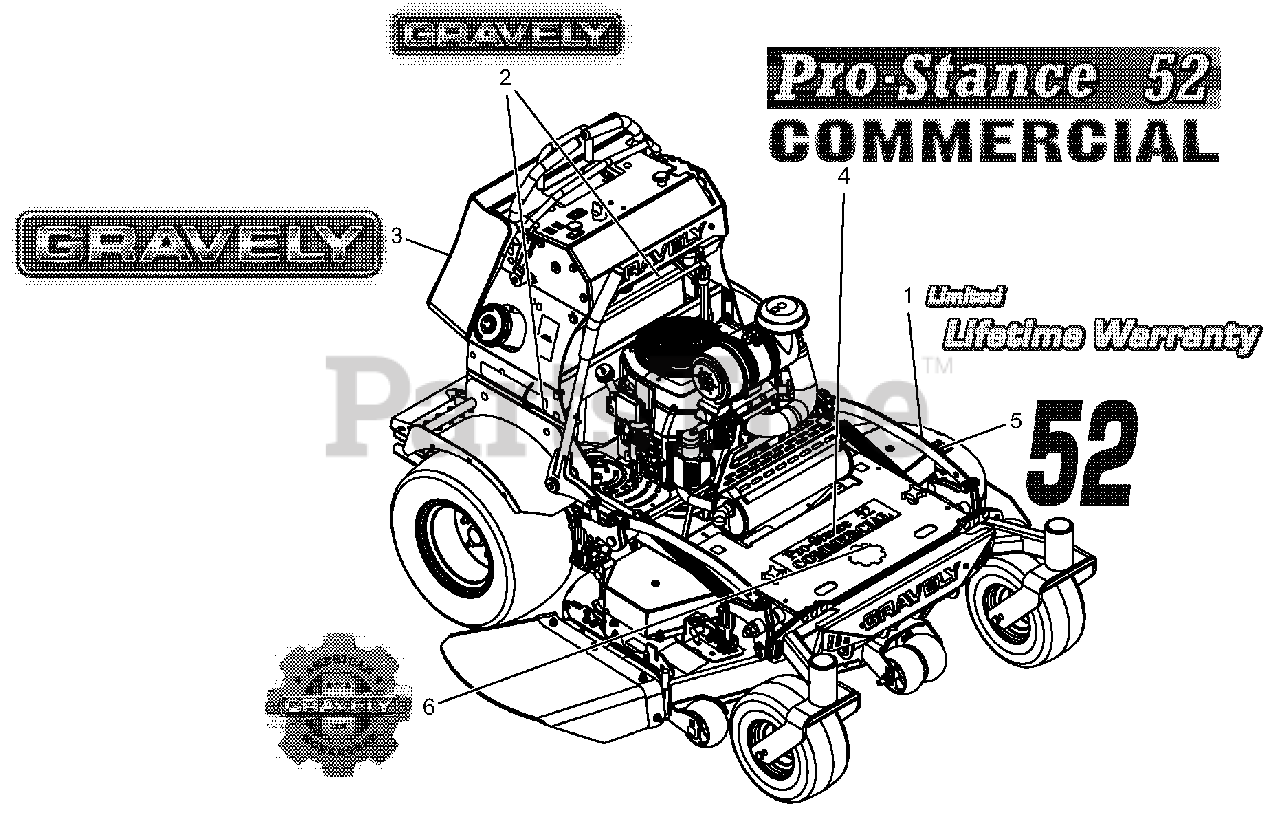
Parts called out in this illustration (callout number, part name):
1	DECAL, LIMITED LIFETIME WARRANTY REV
2	DECAL, 9.5" GRAVELY LOGO
3	DECAL, FUEL TANK-GRAVELY
4	DECAL, PROSTANCE 52" 2011
5	DECAL, 52"
6	DECAL, GRAVELY HERITAGE-LARGE
